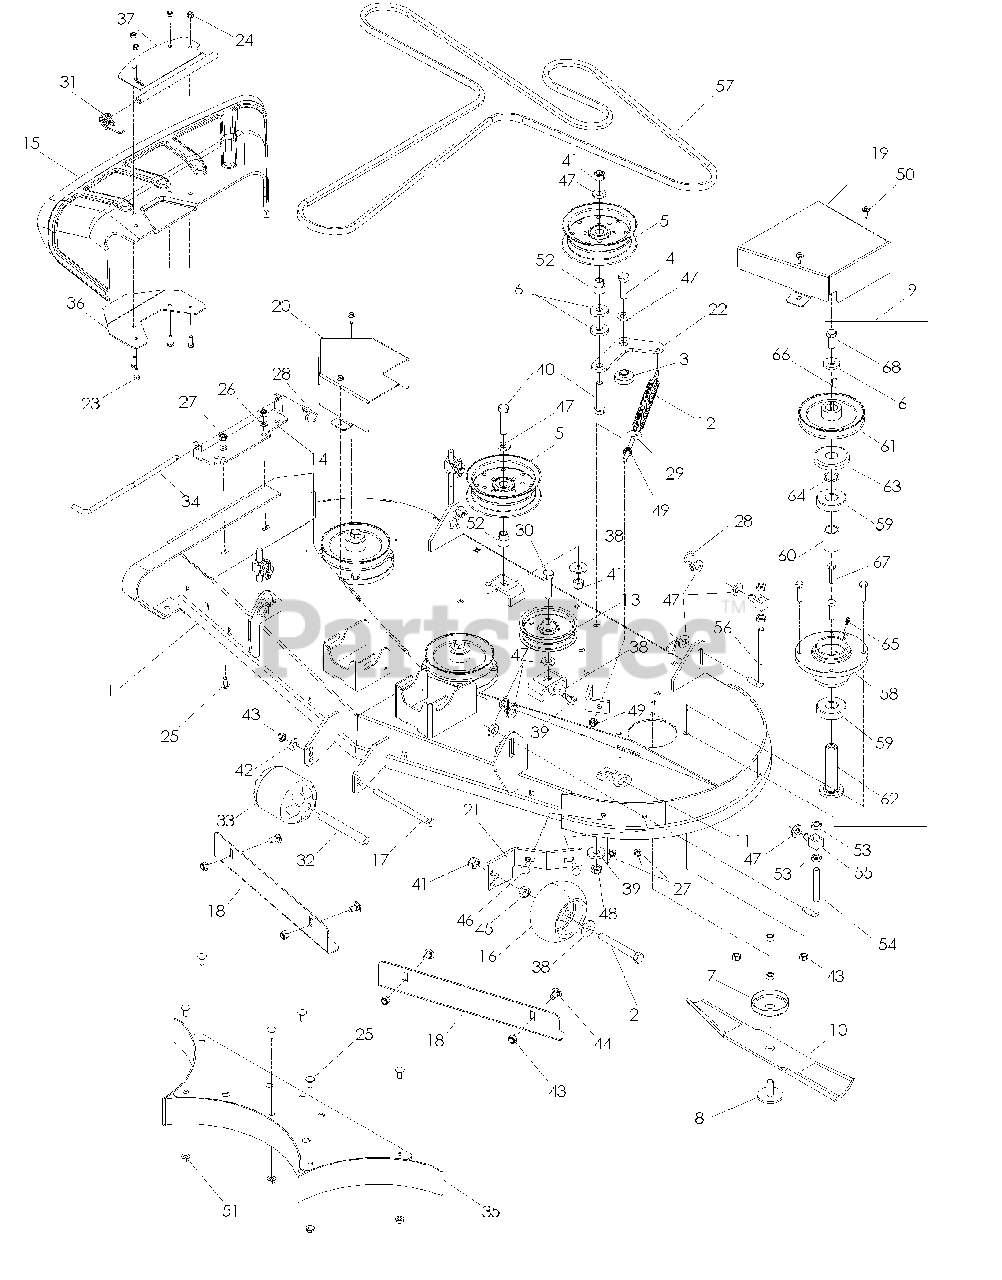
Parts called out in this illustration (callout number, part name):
1	DECK W/DECALS 50" DIX
2	HCS 1/2-13 X 4 GR 5 ZD
3	IDLER SPACER
4	1/2-13X1-3/4 HHB GR. 5
5	PULLEY, IDLER
6	WASHER .525 X 1.375 X .25
7	TRASH GUARD
8	BLADE BOLT
9	SPINDLE, LH 6305 BRG
10	BLD 50`HI LIFT FUSION
11	DECAL, DECK 50"
12	SPRING, DECK BELT
13	PULLEY IDLER
15	44 DEFLECTOR
16	GAUGE WHEEL
17	BOLT 3/8 X 6 GR5
18	BLOW-BY BAFFLE
19	PULLEY GUARD LH
20	PULLEY GUARD RH BLACK
21	BRACKET
22	IDLER ARM
23	HCS 1/4C X 3/4 HCS
24	NUT 1/4-20 NYLOC
25	BOLT 5/16C X 3/4" CARRIAGE
26	FLAT WASHER 5/16 SAE
27	NUT 5/16 NYLOC
28	PIN, COTTER 1 3/4
29	EYE BOLT 5/16 X 3.50
30	BOLT 1/2-13 X 2 HH
31	SPRING, TORSION
32	BUSHING
33	ROLLER 3-3/4 DIA. X 4-1
34	DEFLECTOR PIN
35	W-BAFFLE WLDT.
36	DEFLECTOR BRACKET
37	DEFLECTOR MT BRKT
38	WASH USS FLAT 1/2
39	NUT, 1/2-13 THIN PROF NYL
40	1/2-13X2-1/2 HHB GR5
41	NUT 1/2-13 HEX NYLOC ZD
42	WASHER 3/8 FLAT
43	NUT 3/8-16 NYLOC
44	RHSNB 3/8-16 X 3/4 GR5 ZD
45	NUT HEX 1/2
46	RHSSNB 5/16C X 1.0
47	WASHER 1/2" FLAT
48	WASHER-.533IDX1.37OD
49	NUT 5/16C WHIZ
50	SCREW, TAP & DR #12-14 X 3/4
51	5/16-18 FLANGED L-NUT
52	SPACER - IDLER
53	7/16-14UNC HX JAMNUT
54	L BOLT, S
56	L BOLT, L
57	BELT, DECK
58	DECK HUB MACHINED
59	BEARING - 6305 - 2RS
61	METRIC PULLEY
62	SHAFT SHORT
63	TRASH GUARD
64	HUB PULLEY SPACER
65	ZERK, 3/16, DRIVE IN
66	OUTER SHAFT KEY
67	HHB 3/8-16X1-1/2 GR5
68	1/2-20 UNF X 1 1/4 HHBLT
